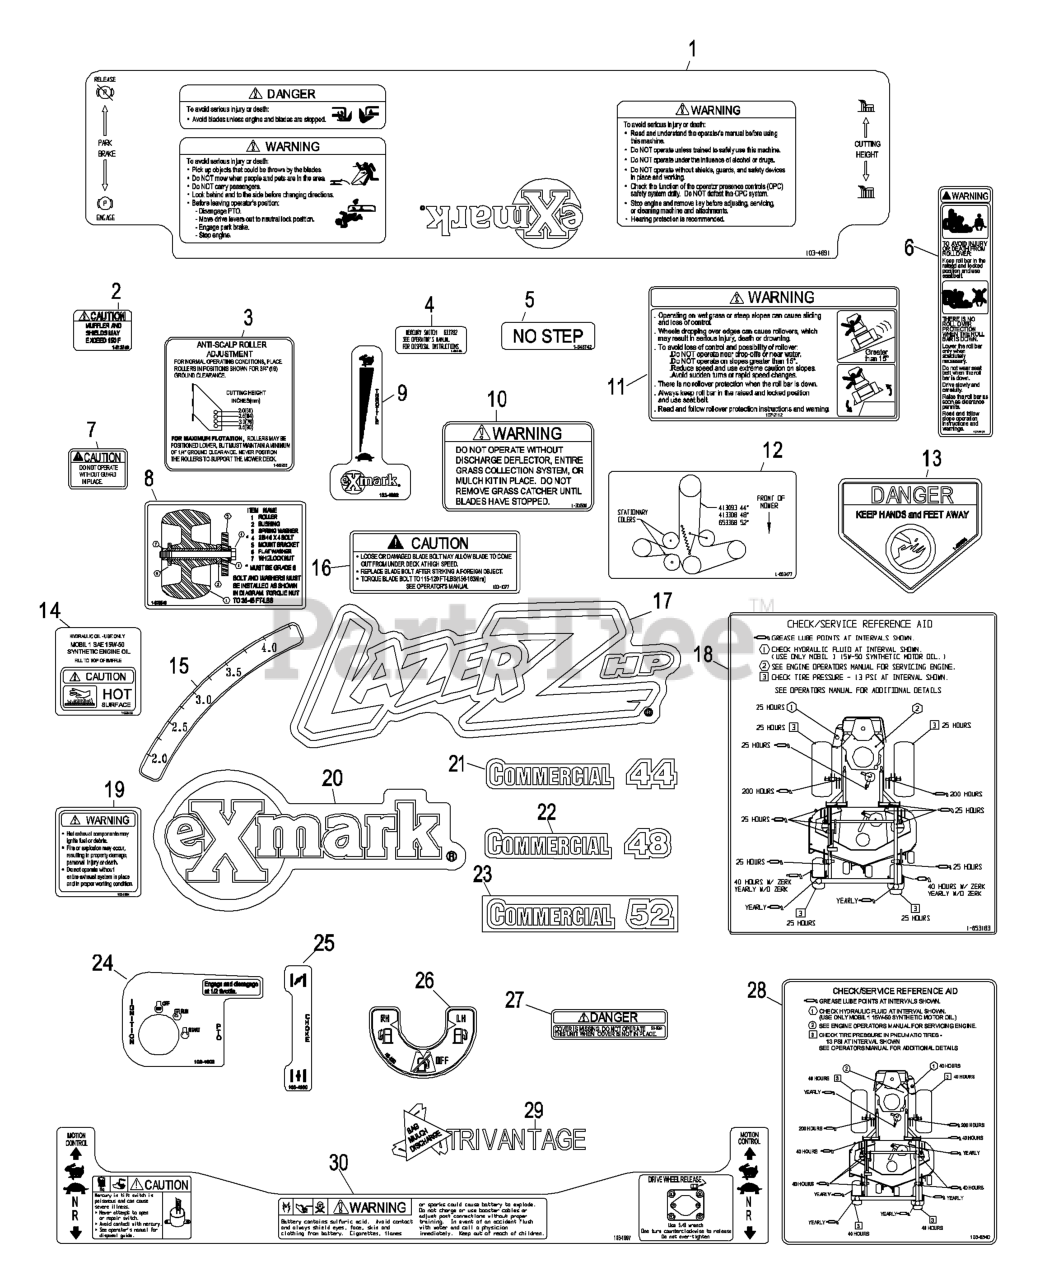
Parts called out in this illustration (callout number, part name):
1	DECAL,CONSOLE LHP
3	DECAL,ANTISCALP
4	DECAL-SWITCH, MERCURY
5	DECAL,NO STEP
6	DECAL-WARNING, FOLDING RO
7	DECAL-GUARD
8	DECAL,ROLLER MOUNTING
9	DECAL,THROTTLE
10	DECAL-WARNING, DISCHARGE
11	DECAL-WARNING
13	DECAL-DANGER
15	DECAL-DECK HEIGHT, INNER
16	DECAL,BOLT TORQUE
17	DECAL,LHP MODEL
19	DECAL-EXHAUST
20	DECAL,EXMARK LOGO
21	DECAL,COMMERCIAL 44
22	DECAL,COMMERCIAL 48
23	DECAL,COMMERCIAL 52
24	DECAL,IGNITION/PTO
25	DECAL,CHOKE
26	DECAL-VALVE, FUEL
27	DECAL-COVER, MISSING
28	DECAL,CHECK/SERVICE LHP
